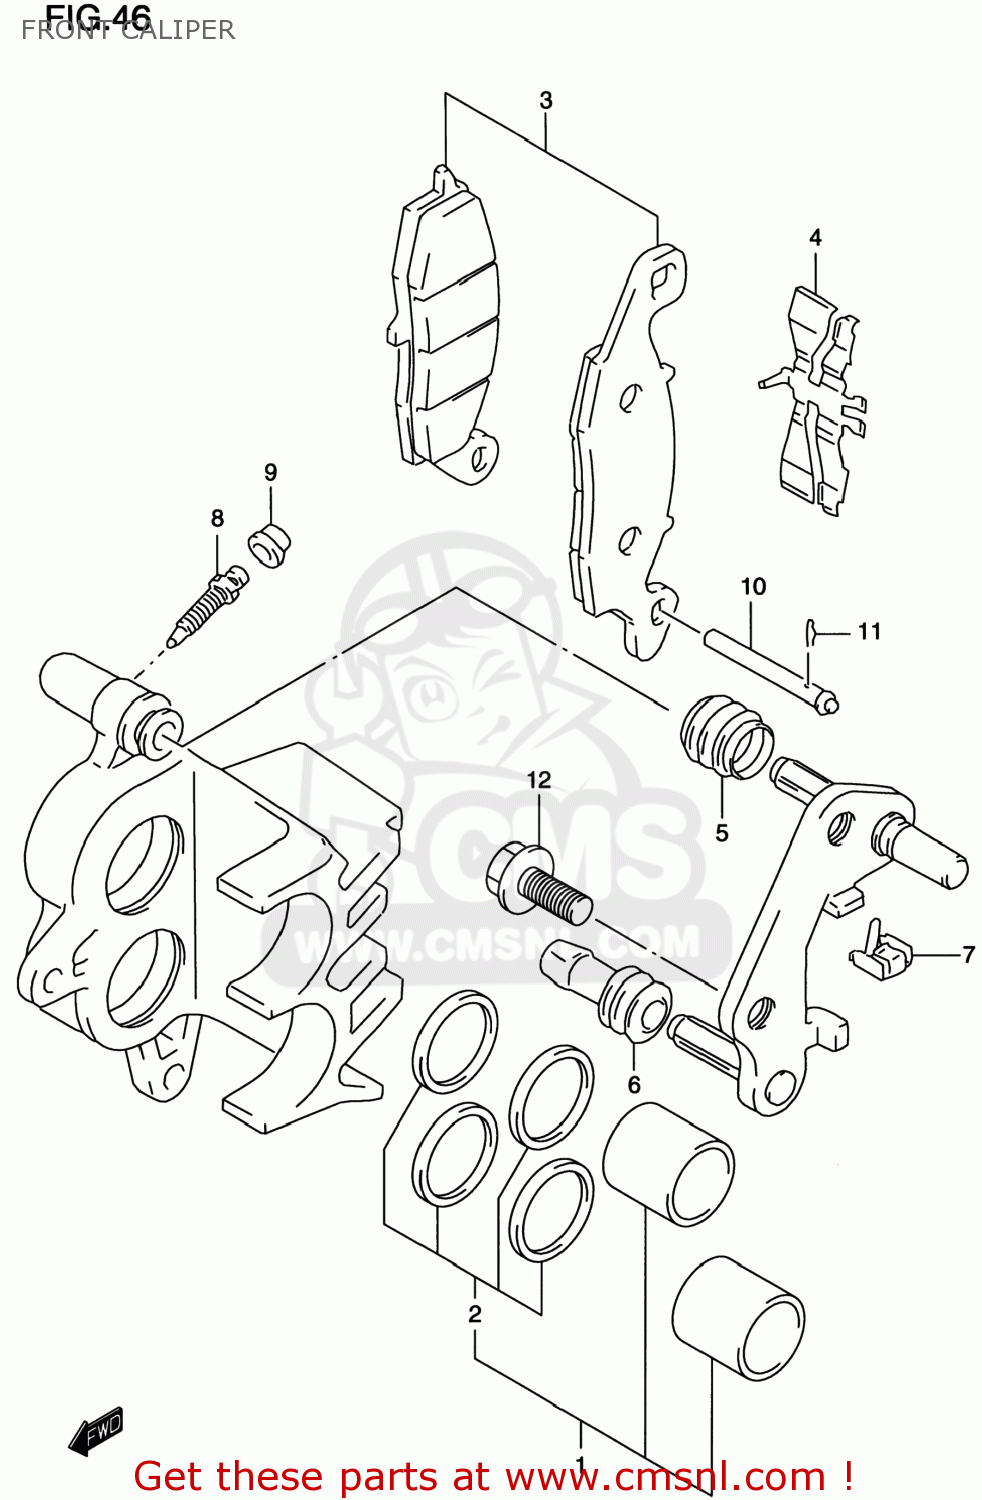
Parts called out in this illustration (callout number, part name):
1	PISTON SET
2	SEAL SET,PISTON
3	PAD SET (NAS)
4	SPRING,PAD,R
5	BOOT,AXLE
6	INSULATOR,AXLE
7	GUIDE,PAD
8	BLEEDER
9	CAP,BLEEDER PLUG
10	PIN,PAD
11	CLIP,PAD PIN
12	BOLT
